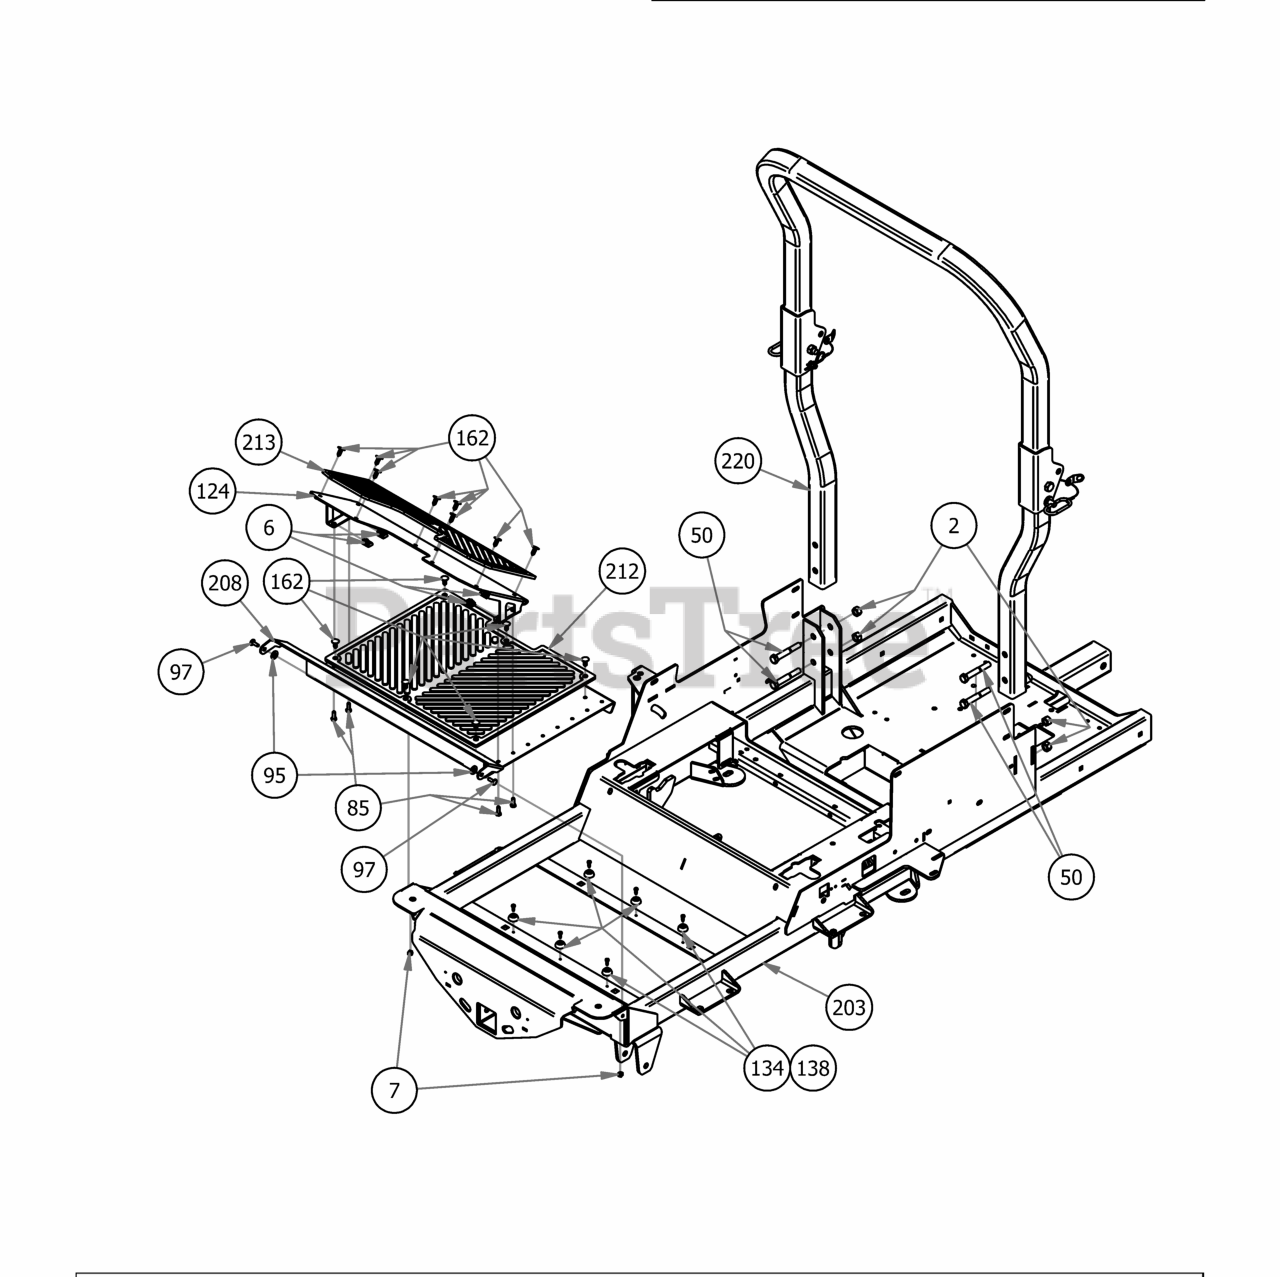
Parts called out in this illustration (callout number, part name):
2	1/2" Center Lock Nut
6	1/4-20 Cage Nut
7	1/4-20 Hex flang lock nut
50	1/2-13 X 3.25 Hex Bolt - Grade 5
85	1/4" x 3/4" Hex Bolt
95	.360 ID Plastic Washer
97	1/4" x 3/4" Carriage Bolt
124	2019 Outlaw Adjustable Foot Plate
134	Button Bumper
138	#10 x 1/2" Self Tapping Screw
162	Ratchet Fastener
203	2019 Horizontal Gas Frame
208	2019 Outlaw Floorboard
212	OUTLAW2019_FLOORMAT
213	FLOORMAT_OUTLAW_2019
220	2019 2X2 Folding ROPS
